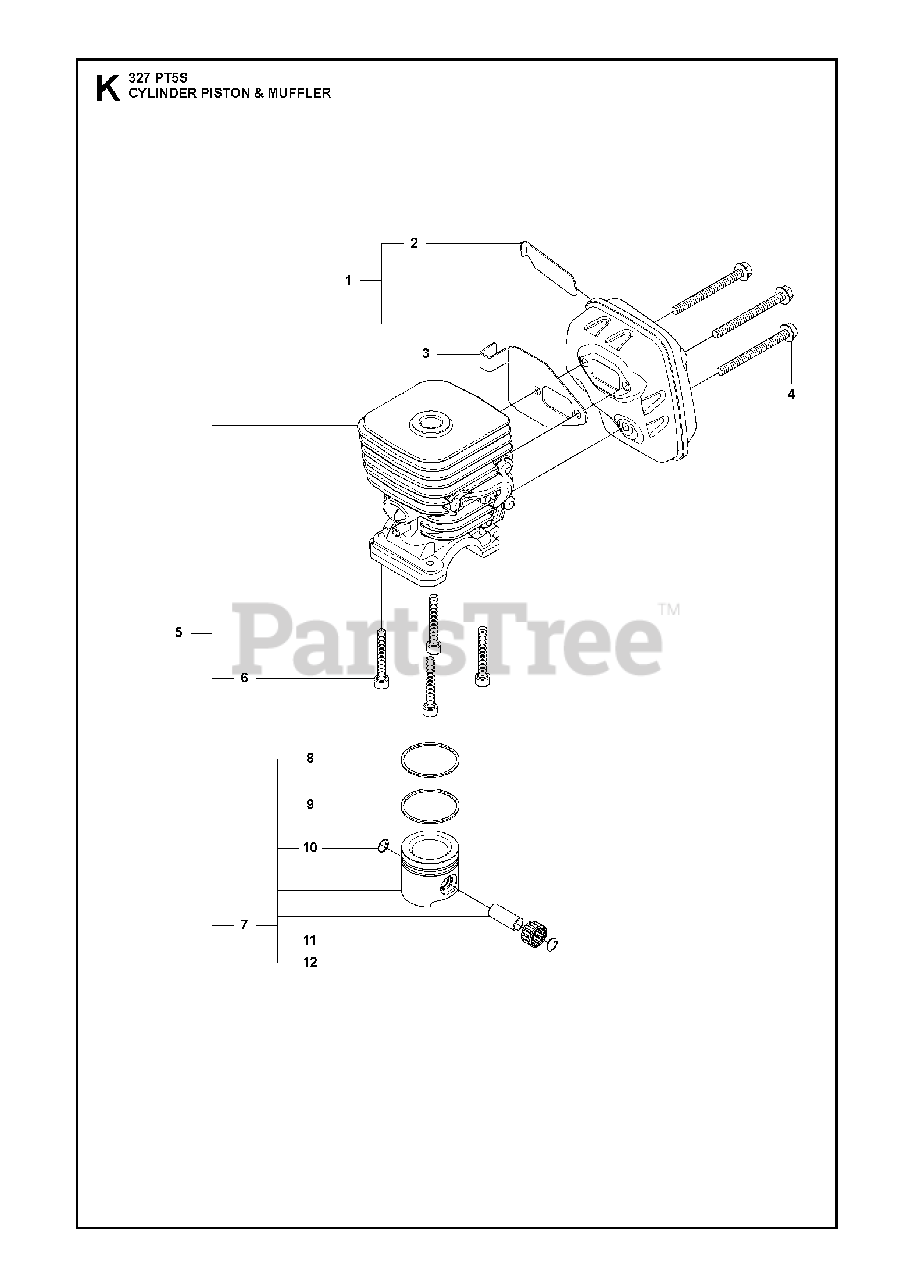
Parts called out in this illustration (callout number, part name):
1	MUFFLER KIT
2	SPARK ARRESTOR SCREEN
4	SCREW EHHFM
5	CYLINDER COMPL
6	%SCREW
7	PISTON
8	PISTON RING
9	PISTON RING
10	CLIP RING
11	BEARING
12	CLIP RING
